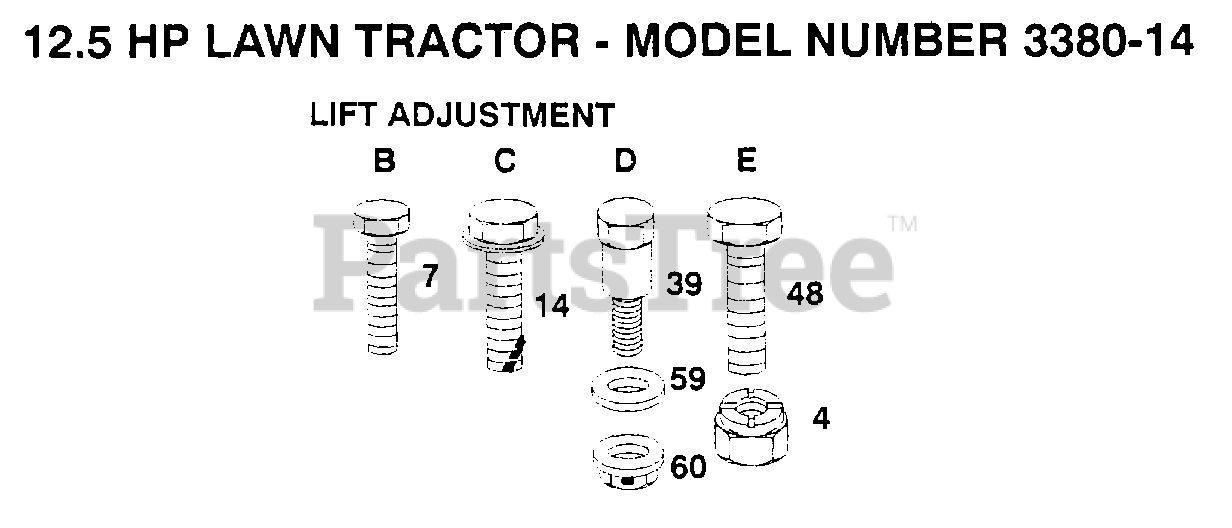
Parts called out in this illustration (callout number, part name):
7	SCREW
14	SCREW HEX CRT
39	"BOLT, SHOULDER LT"
59	WASHER T
60	NUT SPECIAL T
